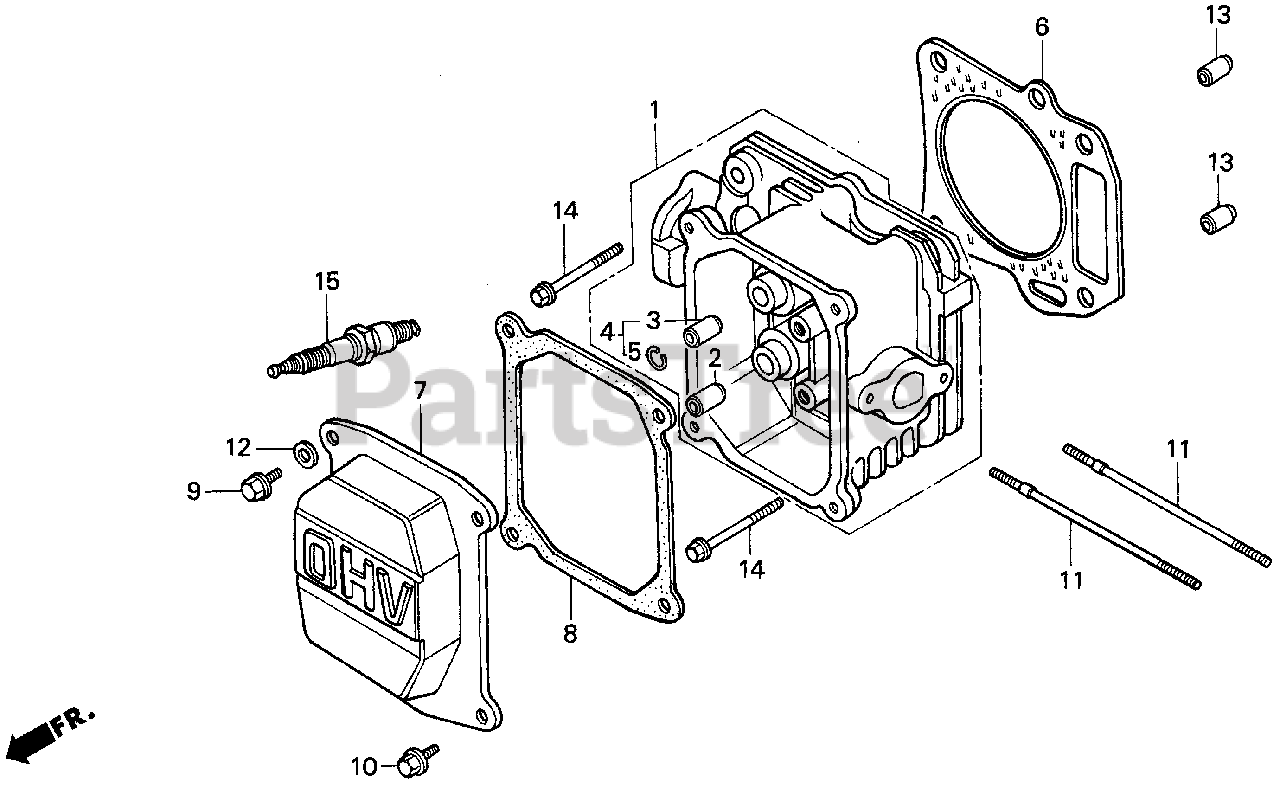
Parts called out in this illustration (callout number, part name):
1	CYLINDER HEAD
2	GUIDE, VALVE (OS)
4	GUIDE, EX. VALVE (OS)
5	CLIP, VALVE GUIDE
6	GASKET, CYLINDER HEAD
7	COVER, HEAD
8	GASKET, CYLINDER HEAD COVER
9	BOLT, FLANGE (6X14)
10	BOLT, FLANGE (6X12) (CT200)
11	BOLT, STUD (6X109)
13	PIN A, DOWEL (10X16)
14	BOLT, FLANGE (8X45)
15	SPARK PLUG (BPR4ES) (NGK)
15	SPARK PLUG (W14EPR-U) (DENSO)
15	SPARK PLUG (BPR5ES) (NGK)
15	SPARK PLUG (W16EPR-U) (DENSO)
15	SPARK PLUG (BPR6ES) (NGK)
15	SPARK PLUG (W20EPR-U) (DENSO)
